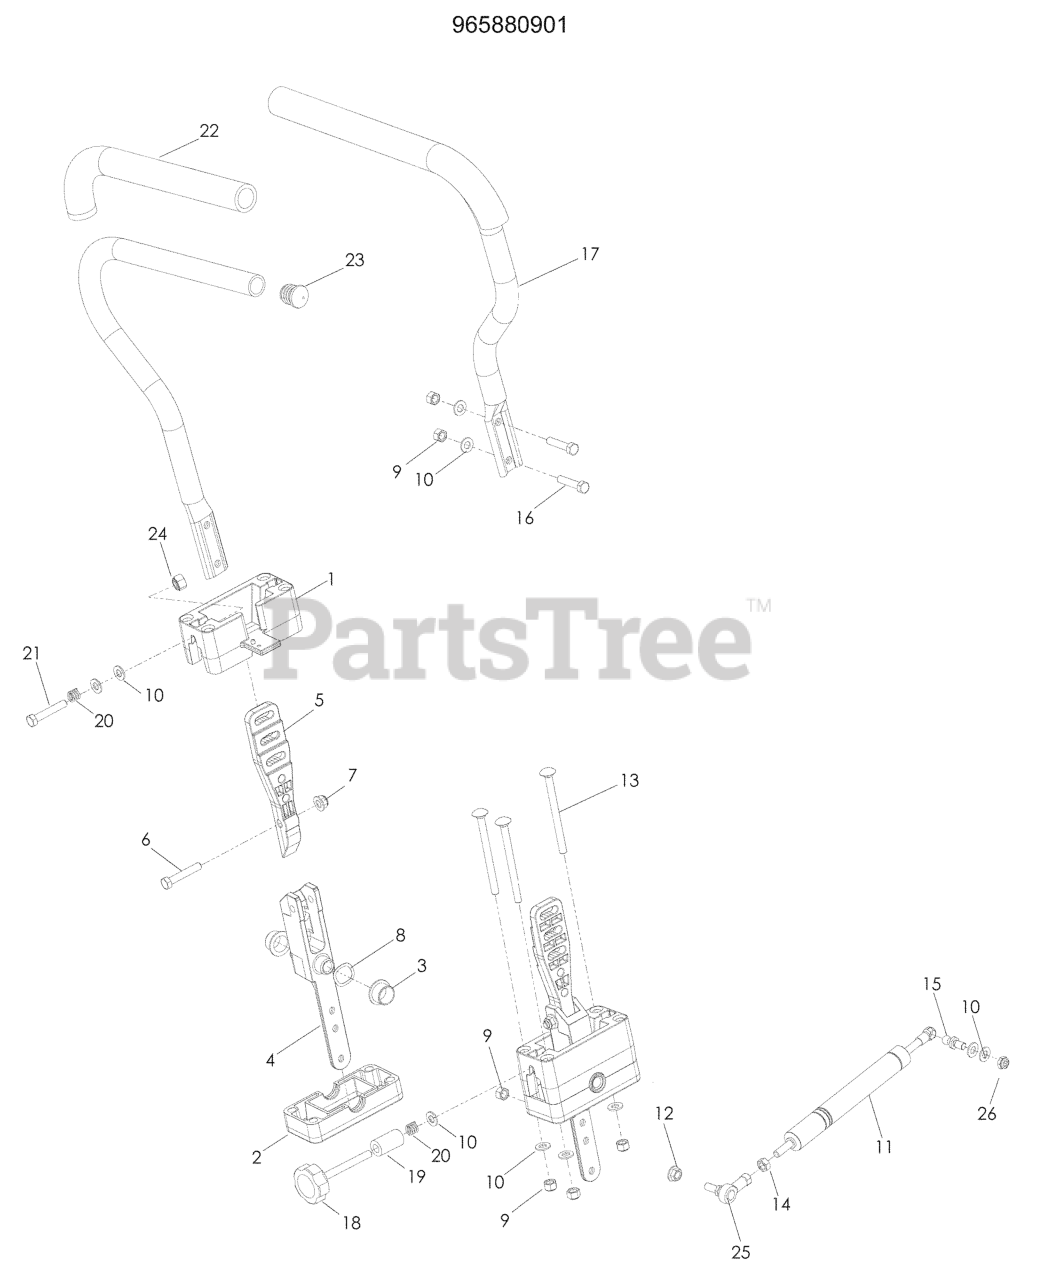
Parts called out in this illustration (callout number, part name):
1	BLOCK, UPPER
2	BLOCK, LOWER
3	BEARING, FLANGE
4	PIVOT.SECTION.DRIVE.CONTROL
5	MOUNT, DR CNTRL HANDLE
6	HCS 5/16C X 1 3/4
7	5/16-18 NYLOC FLANGE NUT
8	WASHER, .825 X 1.087, WAVE
9	NUT 5/16 NYLOC
10	FLAT WASHER 5/16 SAE
11	DAMPENER W/SPRING
12	NUT 5/16C WHIZ
13	RHSNB 5/16-18 X 4 GR 5 ZD
14	NUT M8 X 1.25 STD HEX
15	STUD.BALL.10MM
16	CAPSCREW 5/16 X 1/1/2 HEX HEAD
17	LEVER.DRIVE.W/GRIP
19	DECK LIFT SPACER
21	HCS 5/16-18 X 2 TPBLT GR 5 ZD
22	GRIP, FOAM (GROUND) 15
23	END PLUG 15/16 (BLACK)
24	NUT 5/16C HEX
26	5/16-18 THIN PROF NY
